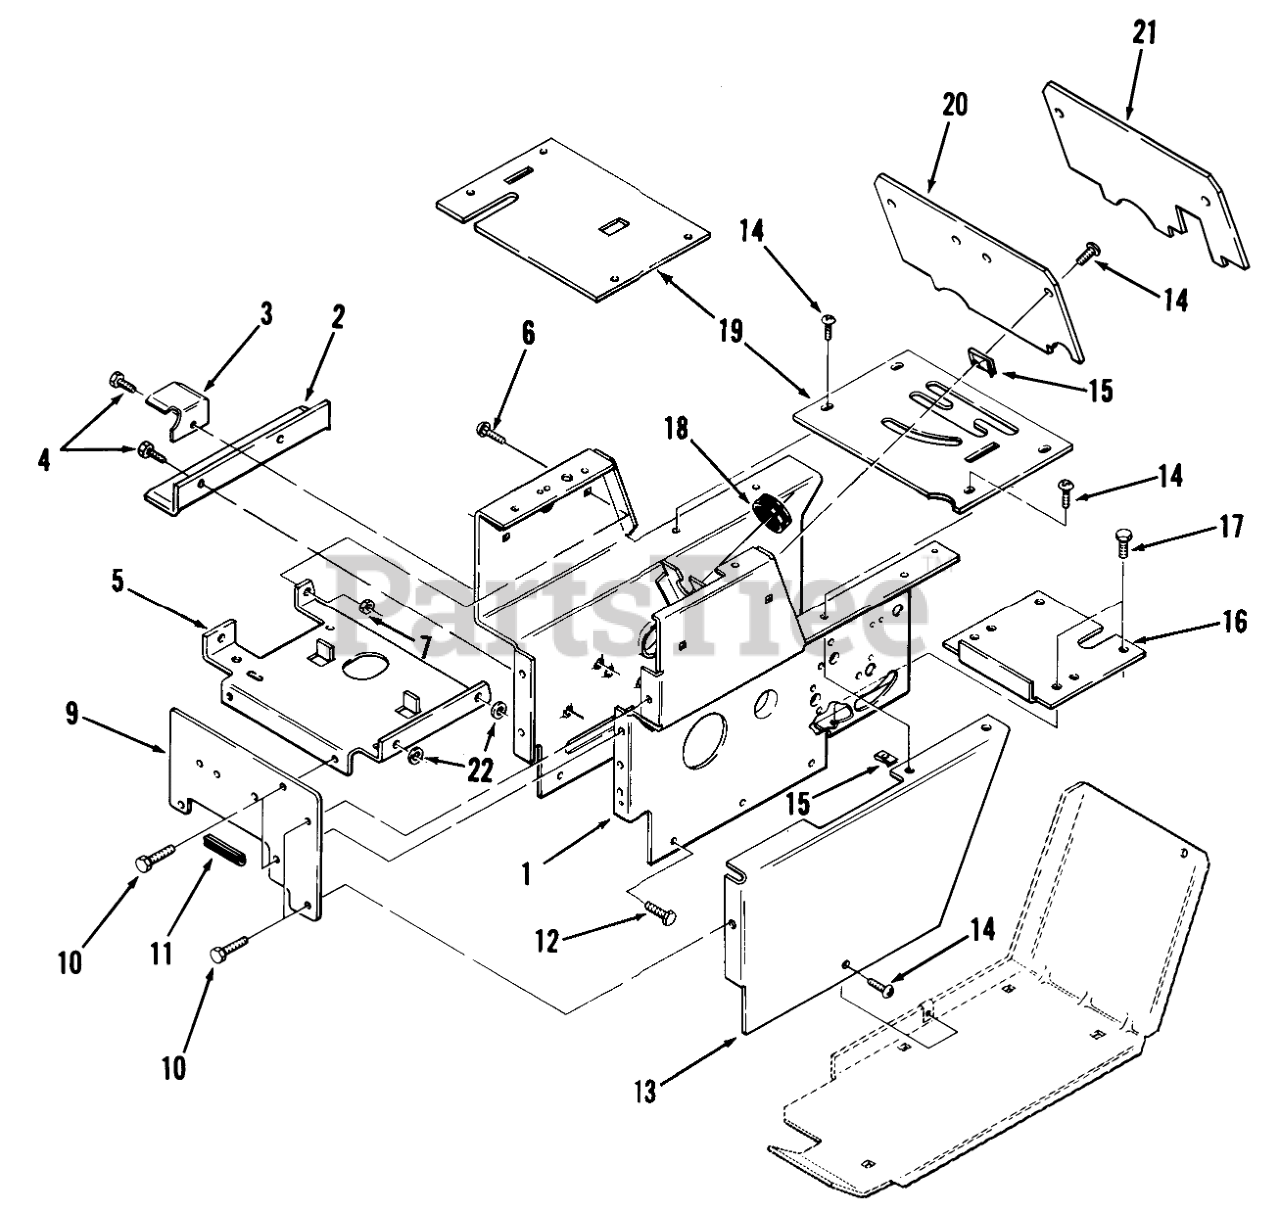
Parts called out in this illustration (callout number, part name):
1	Hoodstand
2	ANGL-BLT GURDB
3	BRCKET-BLT SUTB
3	Belt Bracket
4	SCREW
5	Battery Support Bracket
6	CARRIAGE BOLT -4
7	Nut
9	Front Plate
9	Front Plate C-161 Twin Only
10	SCREW
11	EDGE TRIM 2" 102896
12	SCREW
13	Side Cover LH
14	Screw
16	Cover-Dust
17	SCREW
18	GROMMET
19	PLATE - SHIFT
19	PLATE-SHIFT PATTE B
20	PLATE-HOODSTAND REAR
21	PLATE-HOODSTAND REAR
22	Washer
